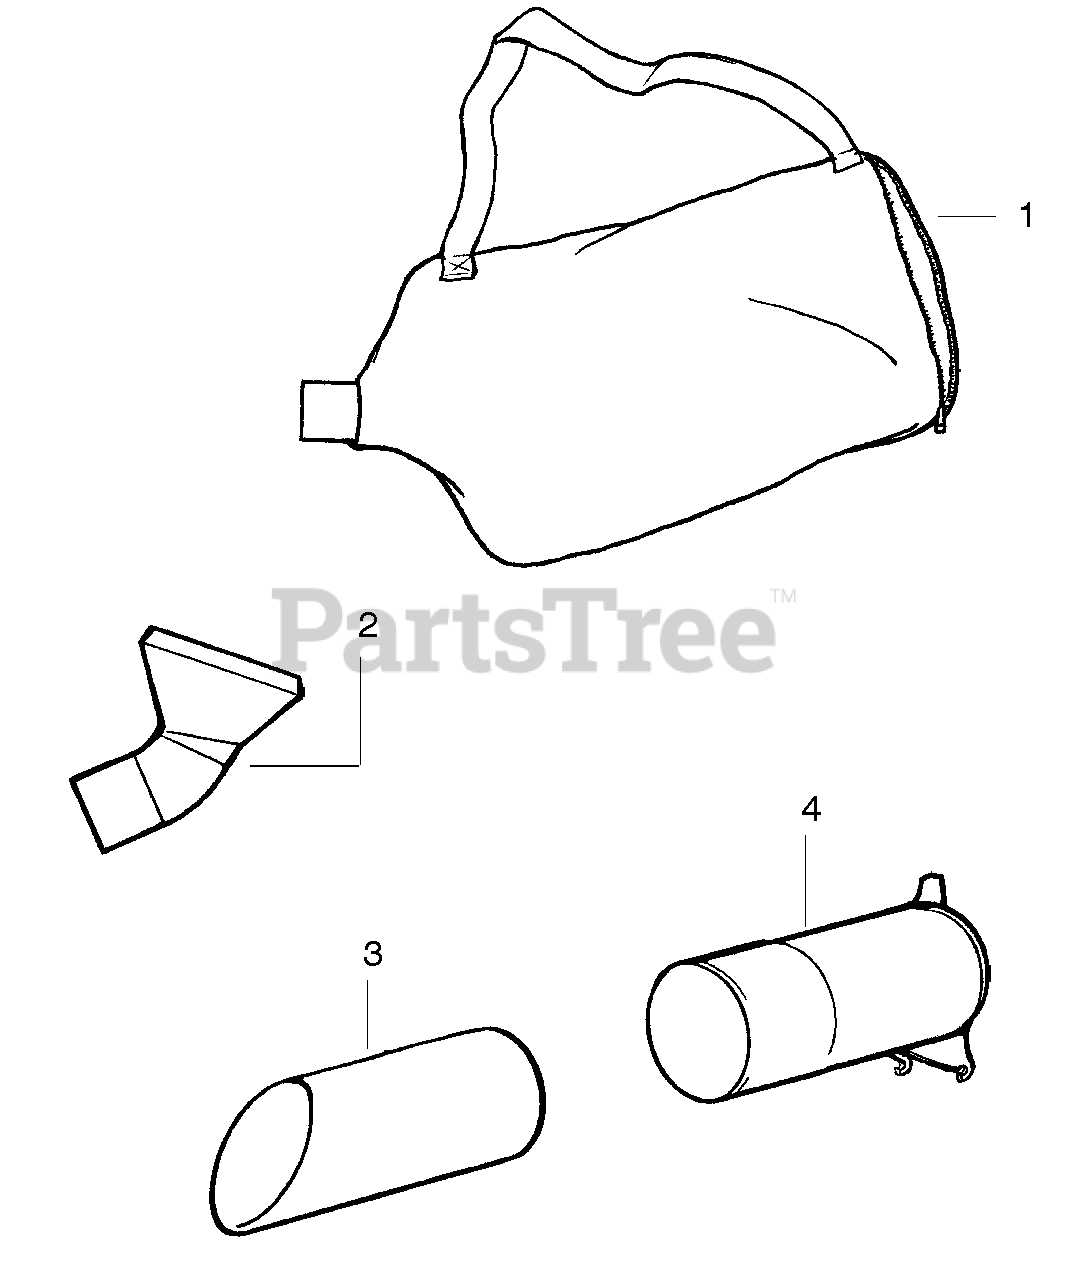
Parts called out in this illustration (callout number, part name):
1	Assy-Vac. Bag w/strap
2	Tube-Elbow Vac
3	Tube-Lower Vac
4	Tube-Upper Vac
